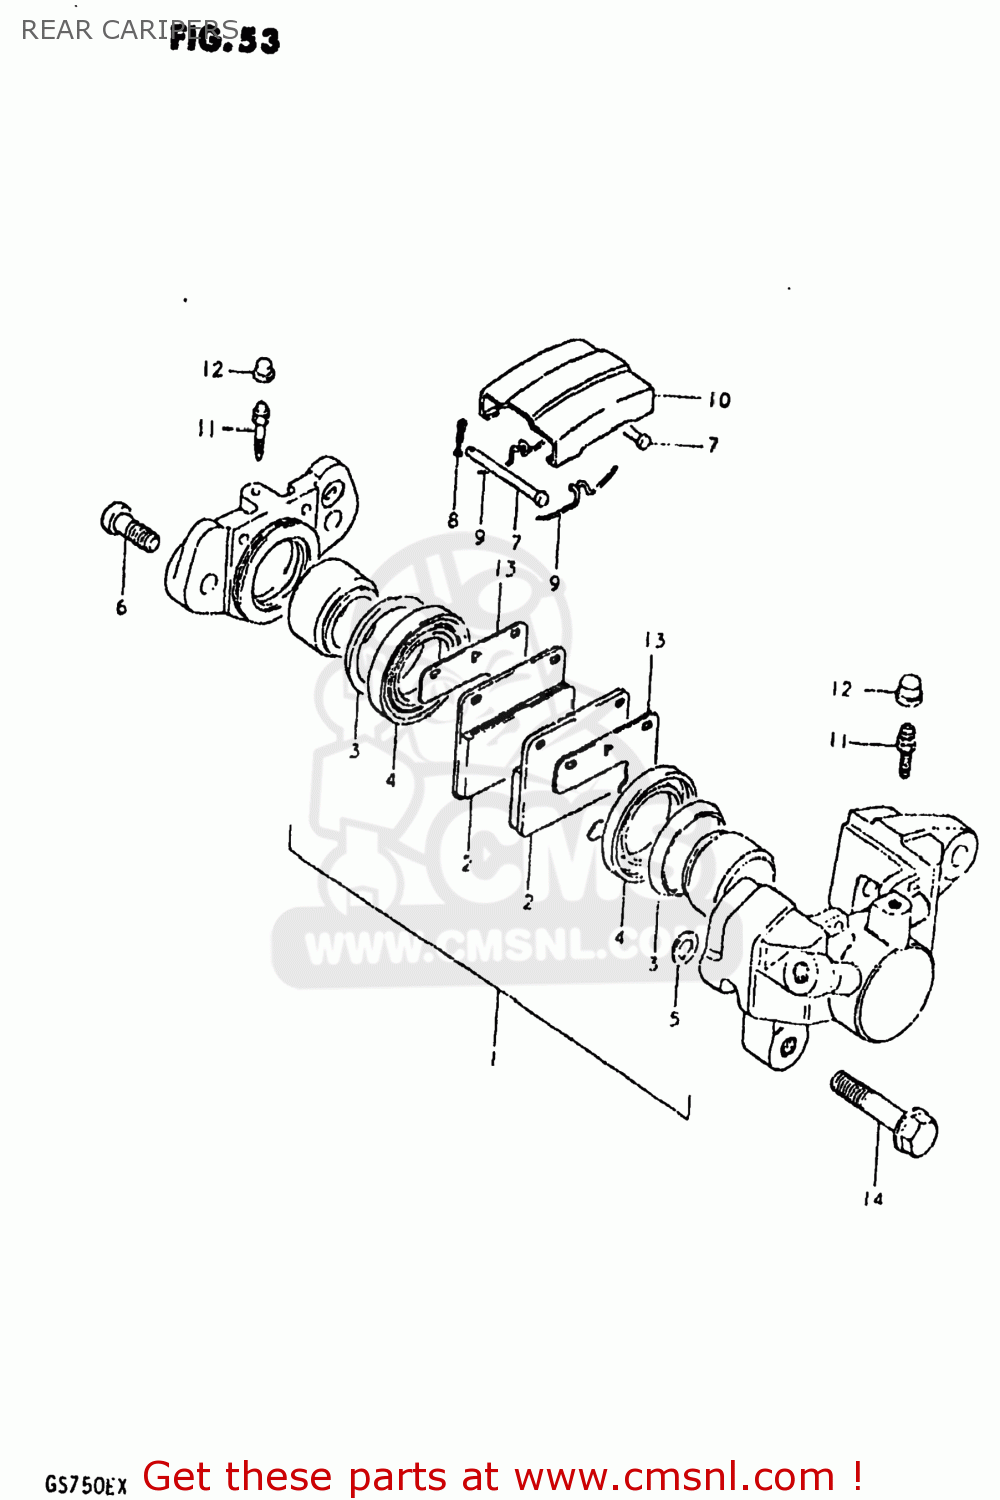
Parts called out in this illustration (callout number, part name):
1	PISTON SET
2	PAD,BRAKE
3	SEAL,PISTON
4	BOOT,PISTON
5	SEAL,PISTON
6	BOLT,HOUSING
7	PIN,PAD
8	CLIP,PAD PIN
9	SPRING
10	COVER,DUST
11	BLEEDER
12	CAP,BREATHER
13	SHIM,RR CALIPER
14	BOLT
